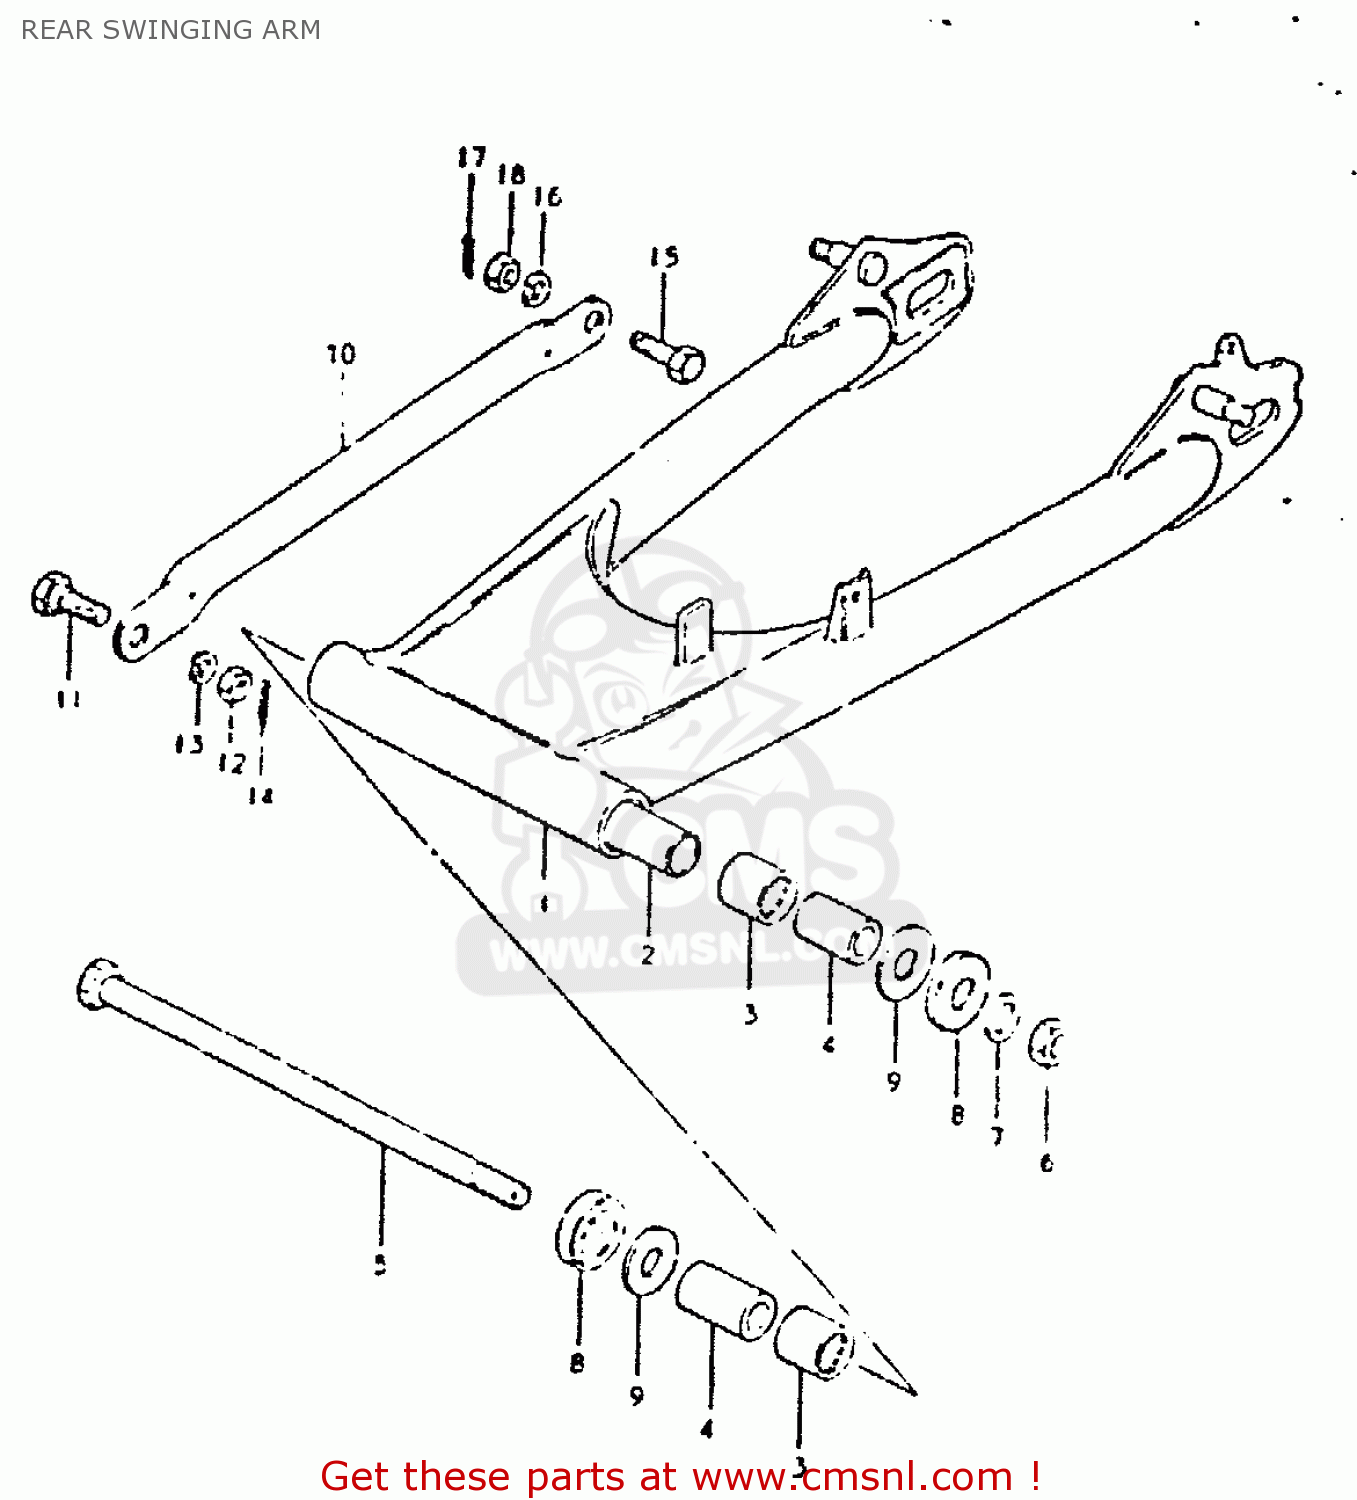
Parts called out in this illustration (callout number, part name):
1	ARM,REAR SWING
2	SPACER,SWINGINGARM CTR
3	BEARING(22X29X30)
4	SPACER,RR SWGARM PIVOT
5	SHAFT,REAR SWING ARM
6	NUT 14MM
7	WASHER
8	CVR,RR SWGARM DUST SEAL(OD:40)
9	WASHER(14.2X34X1)
10	TORQUE LINK,REAR
11	BOLT(10X24.5)
12	NUT
13	LOCK WASHER
14	PIN 20X20
15	BOLT(10X31)
16	LOCK WASHER
17	PIN 20X20
18	NUT
